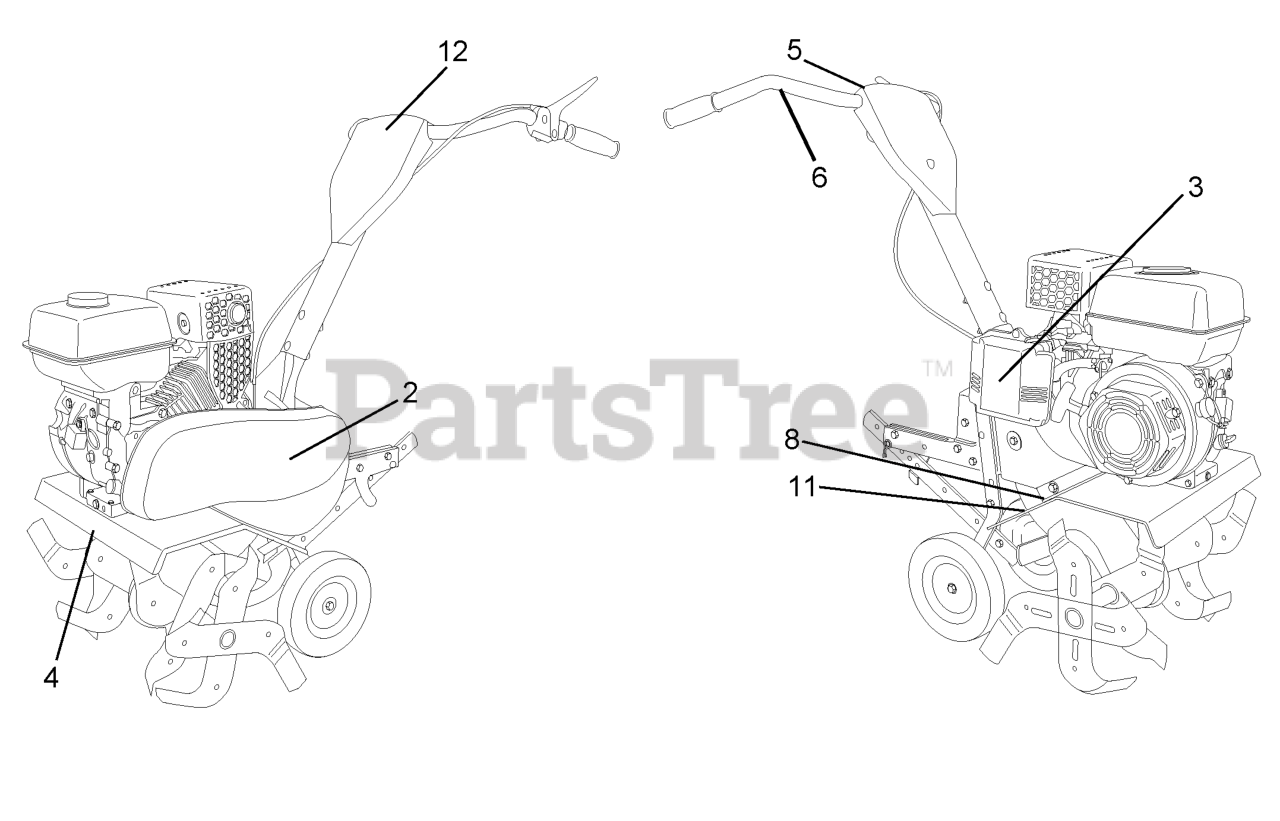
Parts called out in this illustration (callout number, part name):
2	Decal, Logo
3	Decal, Engine AC
4	Decal, Tine Shield
5	Decal, Cntrl Pnl Inst.
6	Decal, Hand Placement
8	Decal, Tine, Shield, Warning
11	Decal, Warning, Rotating Tines
12	Decal, Control Panel
12	Manual, Operator's (English/French)
12	Manual, Parts
